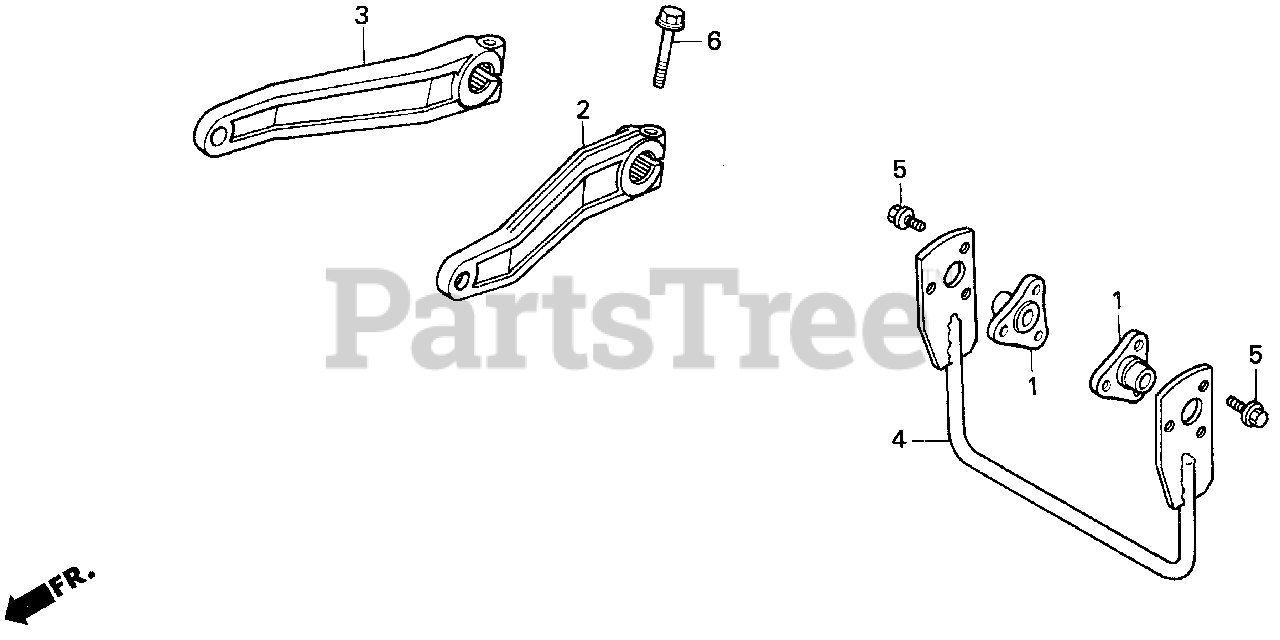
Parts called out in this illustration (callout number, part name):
1	PIVOT, FR. HITCH
2	ARM, L. FR. LIFT
3	ARM, R. FR. LIFT
4	GUARD, TENSIONER
5	BOLT, FLANGE (8X25)
6	BOLT, FLANGE (10X40)
